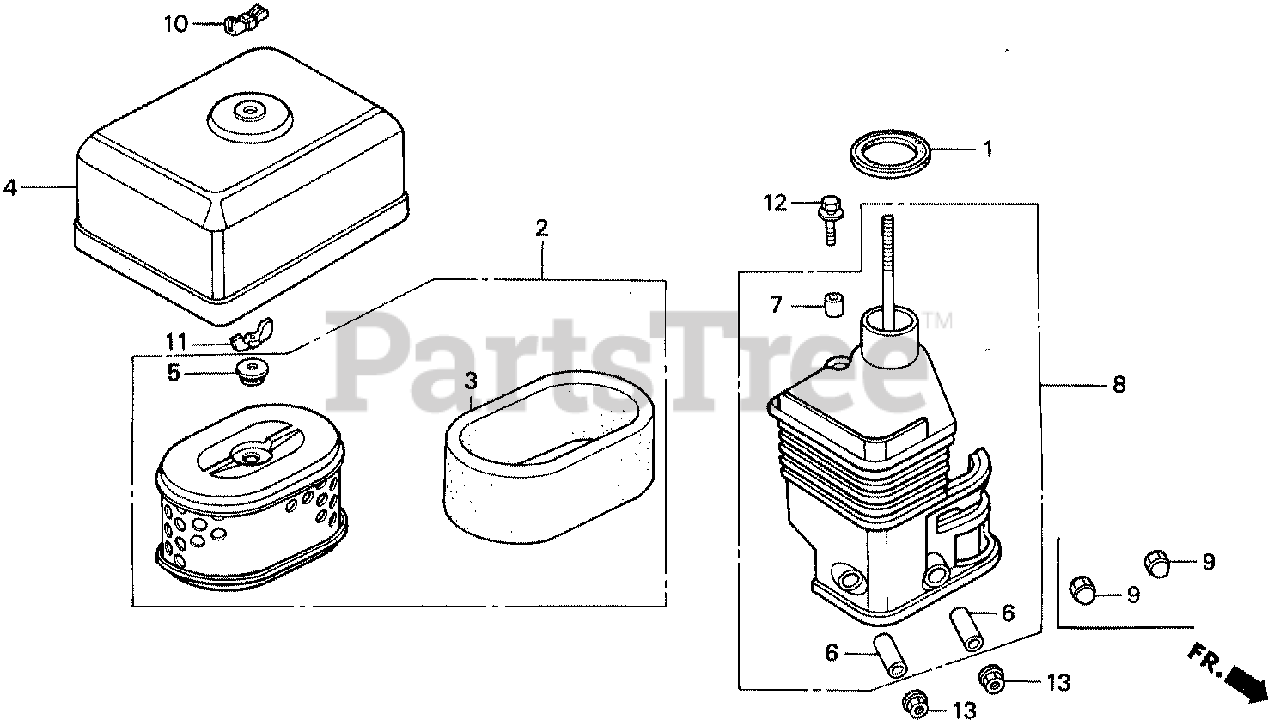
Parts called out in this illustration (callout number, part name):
1	GASKET, ELBOW
2	ELEMENT, AIR CLEANER (DUAL)
3	FILTER (OUTER)
4	COVER, AIR CLEANER (DUAL)
5	GROMMET, AIR CLEANER
6	COLLAR, AIR CLEANER
7	COLLAR B, AIR CLEANER
8	ELBOW, AIR CLEANER
9	NUT, CAP (6MM)
10	WINGNUT, AIR CLEANER COVER
10	WINGNUT (6MM)
10	WINGNUT, TOOL BOX SETTING
11	WINGNUT, TOOL BOX SETTING
12	BOLT-WASHER (6X20)
13	NUT, FLANGE (6MM)
